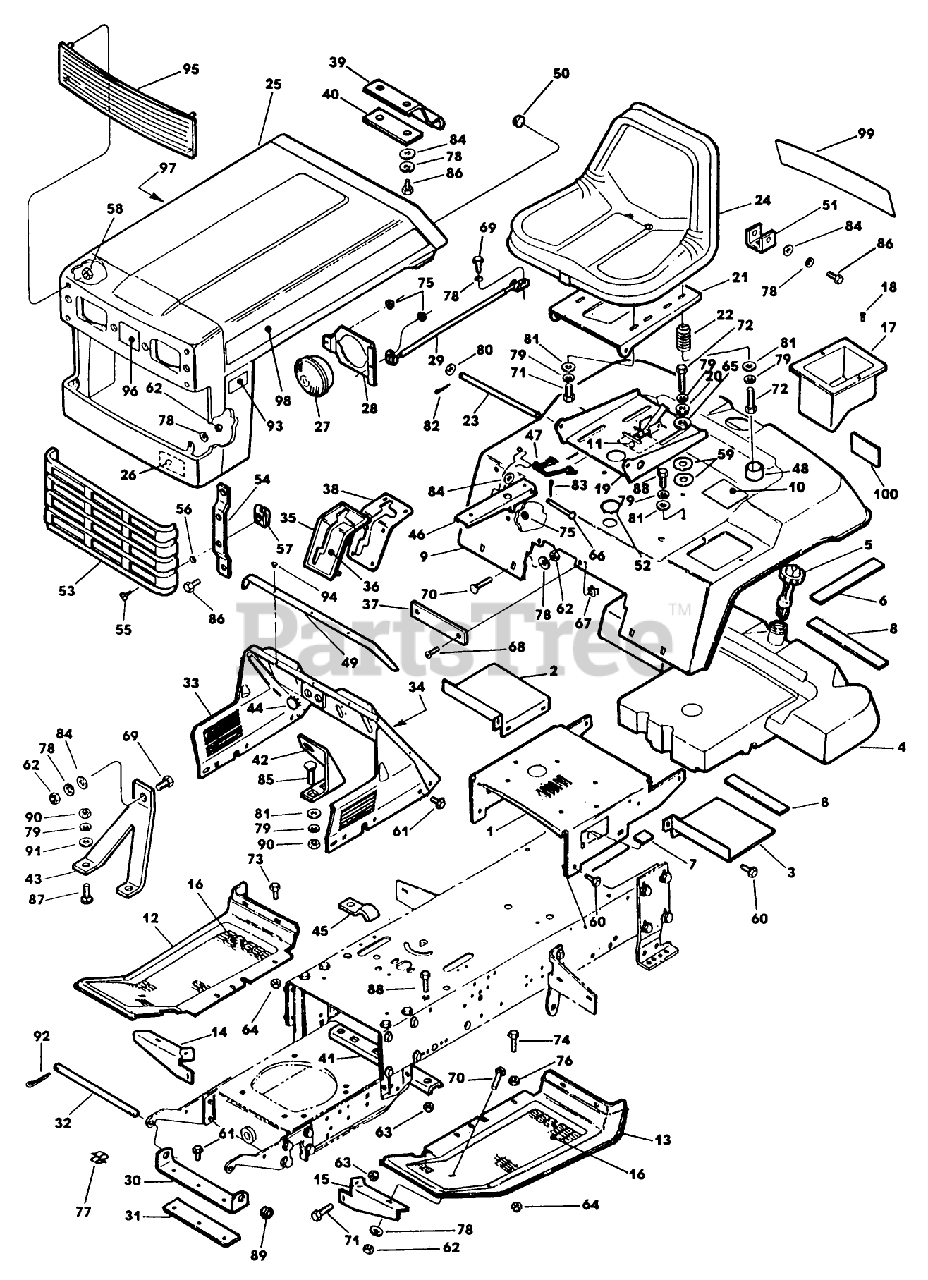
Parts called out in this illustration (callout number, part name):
4	TANK - FUEL
5	GUAGE ASSEMBLY-FUE
8	PAD - FUEL TANK
12	FOOTREST - RH *G
18	Rivet
19	SEAT SUPPORT AY
21	PIVOT AY - SEAT *B
23	PIN
24	SEAT
32	ROD - HOOD PIVOT
43	BRACKET-SUPPORT
46	LATCH - SEAT PAN *B
48	CAP-PROTECTOR
53	INSERT - GRILLE
55	FASTENER-1/4 TURN
59	WASHER-PLASTIC
62	NUT
63	NUT
64	NUT-LOCKING
66	PIN
67	NUT-SPEED
68	SCREW - PPH
69	SCREW
71	SCREW - HEX
72	SCREW
76	NUT
77	CLIP
80	WASHER
86	SCREW-HH
87	BOLT - CARRIAGE
89	BEARING-NYLINER
90	NUT SS
98	DECAL - HOOD LH
100	REFLECTOR
